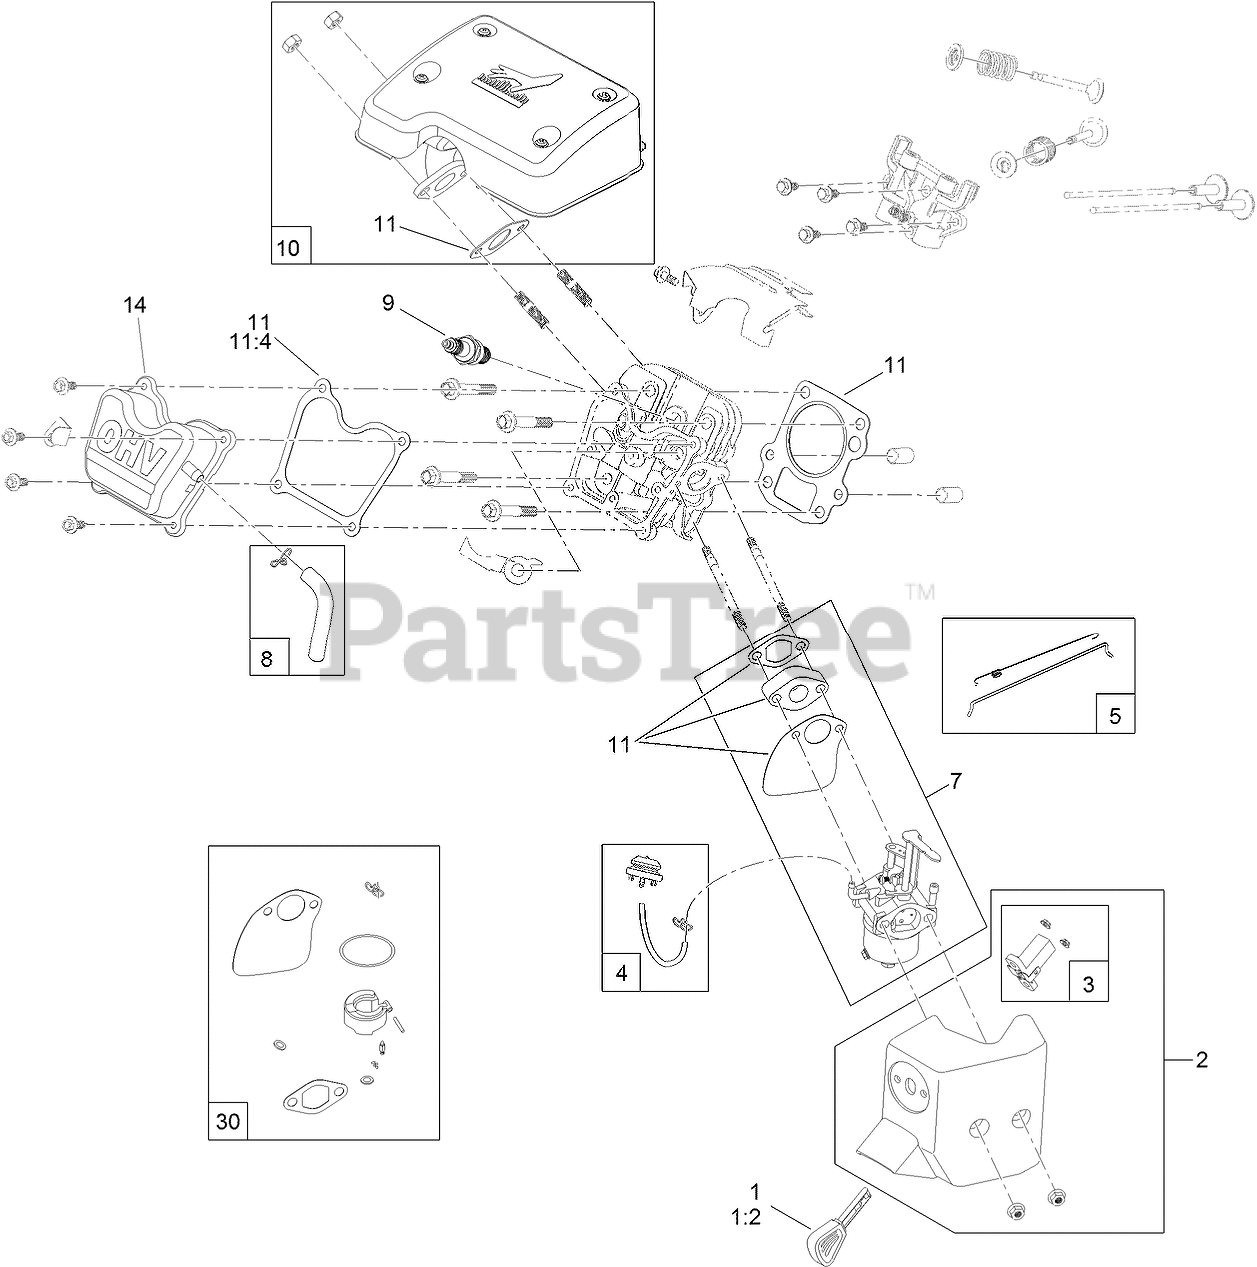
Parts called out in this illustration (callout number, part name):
1	KEY AND LANYARD KIT
2	HEATER BOX KIT
3	SWITCH KIT
4	PRIMER BULB KIT
5	GOVERNOR KIT
7	COMPLETE CARB SERVICE KIT
8	BREATHER TUBE KIT
9	SPARK PLUG
10	MUFFLER KIT
11	GASKET, SEAL AND O-RING KIT
11:4	GASKET-COVER, VALVE
14	VALVE COVER ASM
30	CARBURETOR REPAIR KIT
